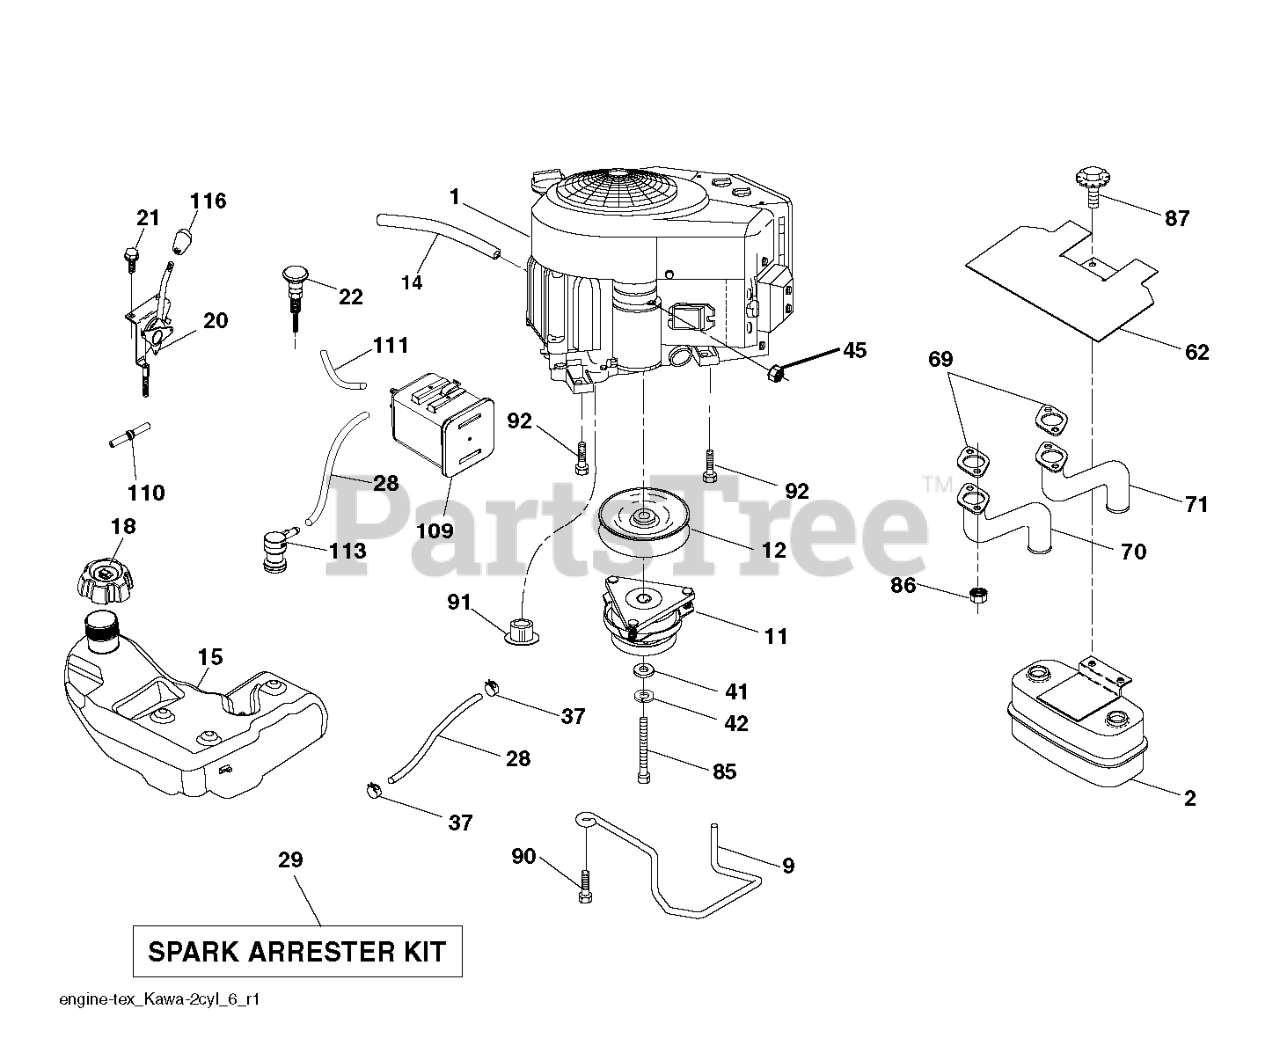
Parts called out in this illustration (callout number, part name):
2	MUFFLER.TWIN.CYL.LOW.TONE
9	KEEPER.BELT.ENGINE.4.2
11	CLUTCH.ELECTRIC.LT.48"*
12	PULLEY.ENGINE.TUFFTORQ
14	TUBE, DRAIN OIL ASM.
15	TANK.ASM.FUEL.3GA.CARB
18	RP CAP ASM
20	CONTROL.THROTTLE.PRO.
21	SCREW.#10 X 0.750.BOS
22	CONTROL.CHOKE.ERGO.PUSH-IN.BLA
28	LINE.FUEL.64"REAR.EMIS
29	KIT.SPARK ARRESTOR 794945 B&S
37	HOSE CLAMP
42	LOCKWASHER
45	NUT
62	SHIELD.HEAT.MUFFLER
70	TUBE.EXHAUST.LH.FR961/FR730
71	TUBE.EXHAUST.RH.FR961/FR730
85	BOLT HEX 7/16-20X4-1/4"
86	NUT.HEX.FLANGE.TOPLOCK
87	BOLT 5/1618UNC X 3/4 W/ SEMS
90	SCREW 3/8-16X1
91	BUSHING.1.375OD
92	SCREW 3/8-16X1
109	CANNISTER, CARBON
110	VALVE.ASM.ANTI-SLOSH
111	RP PURGE LINE
113	VALVE.SLANT.CARTRDG.90 DEG.TEX
116	KNOB - SHIFT
